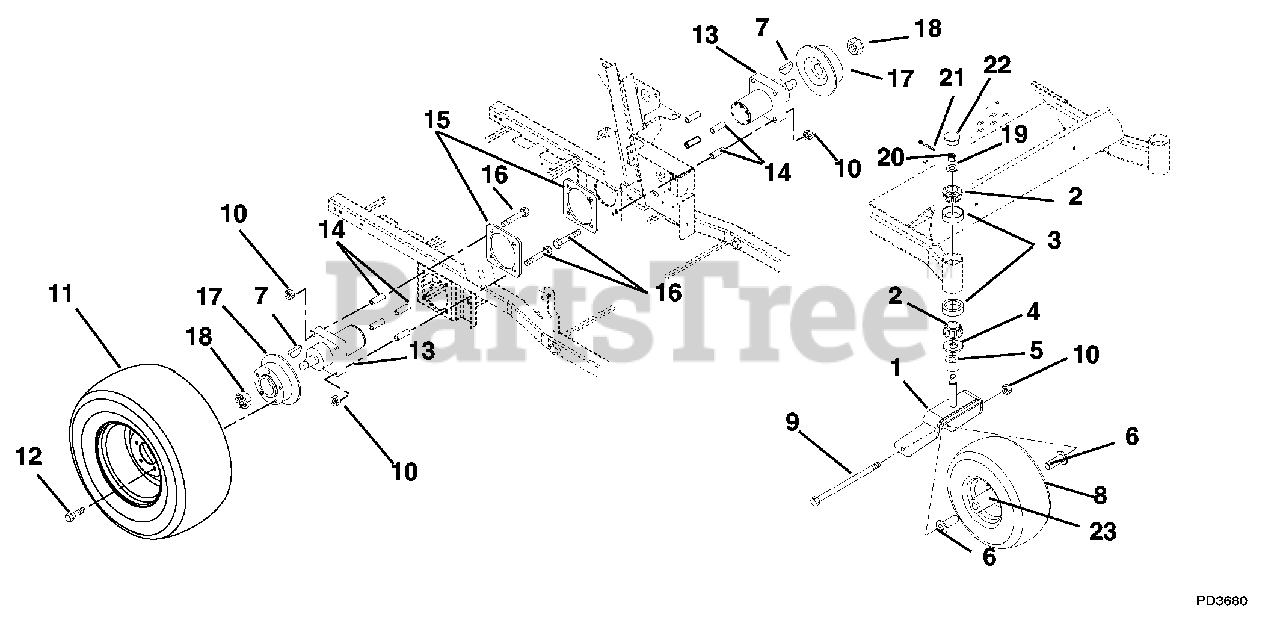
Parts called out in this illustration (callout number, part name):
1	Fork
2	Bearing, Cone with Grease
3	Bearing, Cup 1.980 x .420
4	Bearing Seal 1.5 x 2 x .18
5	Spacer, PM, 1.03 I.D. x 1.5 O.D. x .375
6	Spacer, Wheel
7	Key, Woodruff .31 x 1.00
8	Wheel/Tire Assembly
8	Tire, 15 x 6-6
9	Bolt, Hex .50-13 x 9.00 Grade 5
10	Nut, Locking Top Flange .50-13
11	Wheel, Tire 23 x 10.50 - 12 Multi-Trac (043, 044, 054, 311)
11	Wheel, Tire Assembly 23 x 10.50-12 (051, 054, 055)
11	Tire 23 x 10.50 (043, 044, 051, 054, 055, 311)
11	Wheel, Tire Assembly 23 x 9 50-12 (042, 310)
11	Tire, 23 x 9.50-12 Multitrac (042, 310)
12	Bolt, Lug Grade 8; .50-20 Unf x .75 Long 60 Degree
13	Hydraulic Wheel Motor
14	Bushing, Sleeve .513 x .748 x 2.13
15	Plate, Motor Support
16	Bolt, Hex .50-13 x 5.00 Grade 5
17	Hub and Disc
18	Nut, Lock Jam Patch
19	Washer, Flat Steel .755 x 1.375 x .062
20	Nut, Slotted .75-16
21	Pin, Cotter .16 x 1.00
22	Cap, Dust
23	Bearing, 25MM I.D. x 52MM OD x 15MM
